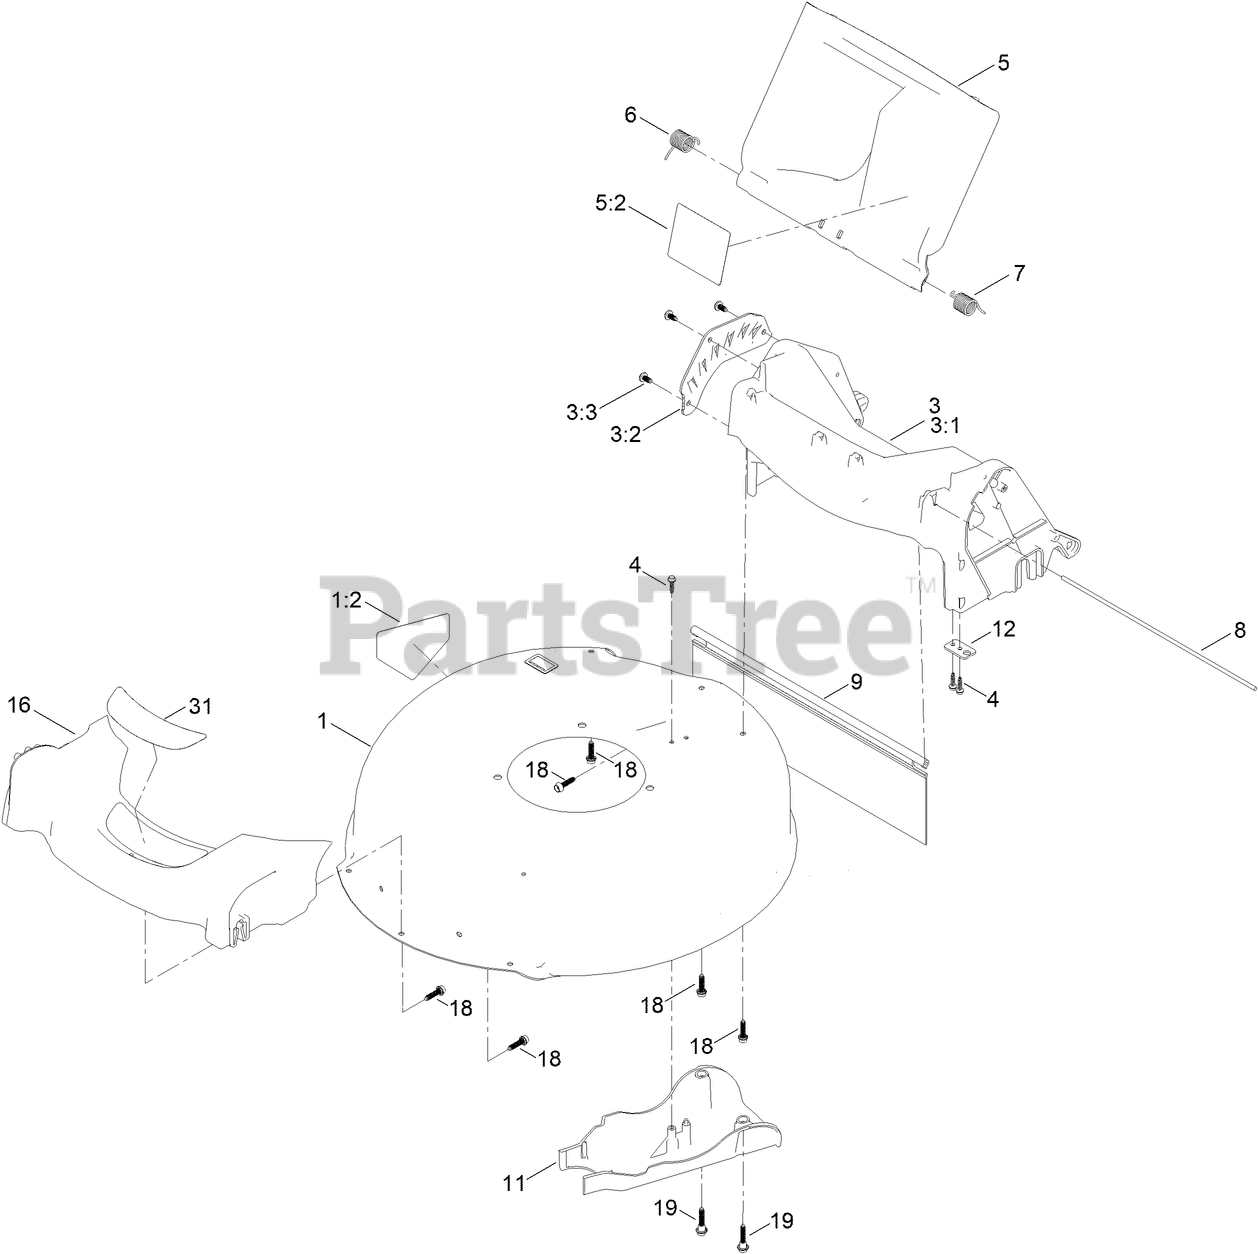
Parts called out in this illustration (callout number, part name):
1	HOUSING ASM
1:2	DECAL-DANGER
3	CHUTE ASM
3:1	CHUTE-SP/AWD, 21 IN
3:3	SCREW-PLASTIC,PH
4	SCREW-HWH
5	REAR DEFLECTOR ASM
5:2	DECAL-WARNING
6	SPRING-TORSION
7	SPRING-TORSION
9	SHIELD-TRAILING
11	COVER-BELT
12	BRACKET-CABLE
18	SCREW-FLANGE, PLASTIC
19	SCREW-SHOULDER, HHF
31	DECAL-DECK
